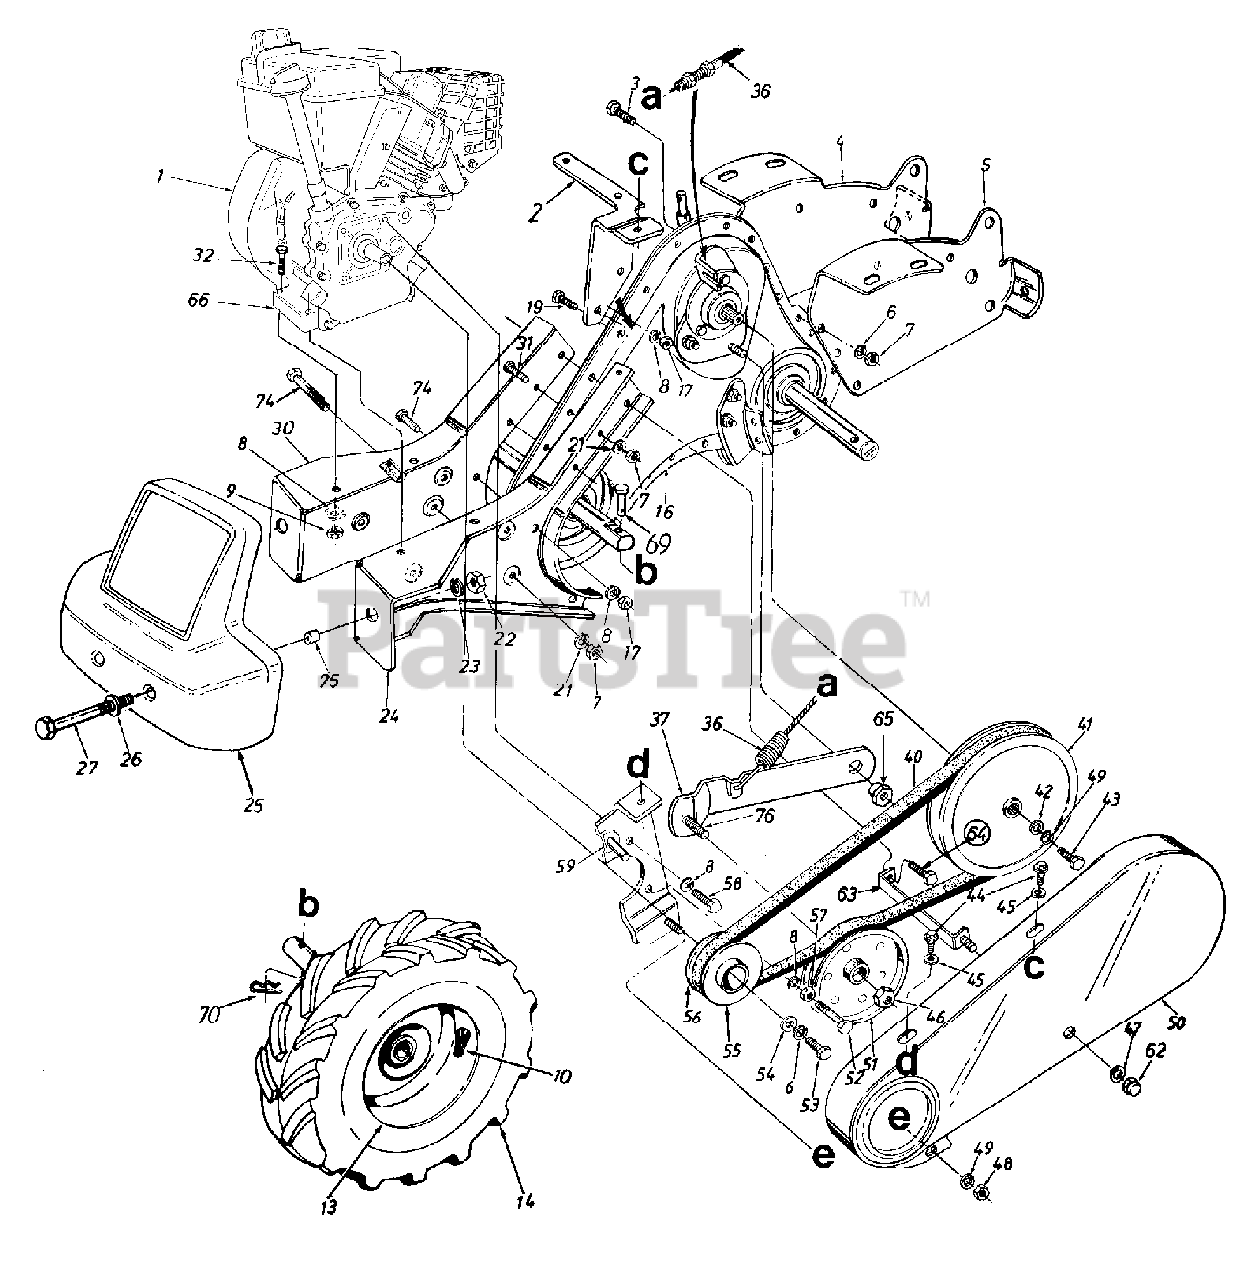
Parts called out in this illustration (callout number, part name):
1	Engine
7	Hex Nut 3/8-16 Thd.
8	L-Wash. 5/16" I.D.
9	Hex Nut 5/16-18" Thd.
10	Air Valve
16	Gear Case Ass'y. Comp.
19	Hex Bolt 5/16-18 x 1" Lg.
22	Hex Nut 1/2-20
23	L-Wash. 1/2" I.D.
26	Fl-Wash. .510" I.D. x 1.0"
27	Hex Bolt 1/2-20 x 5.5" Lg.
32	Hex Bolt 5/16-18 x 2.75"
36	Clutch Control Cable 46" Lg.
37	Idler Bracket
40	"V"-Belt
41	Fl-Pulley 8" O.D.
42	Fl-Wash. 1/4" I.D. x .93" O.D.
43	Hex Bolt 1/4-28 x .75" Lg.
44	Hx Wash. S-Tap Scr 1/4-20 x .50".
45	Fl-Wash. .281" I.D. x .625"
46	Jam Cnter L-Nut 3/8-16 Thd.
47	Fl-Wash. .266" I.D. x .625" O.D.
48	Hex Nut 1/4-20 Thd.
49	L-Wash. 1/4" I.D.
50	Belt Cover
51	Fl-Idler w/Flanges 3.75" O.D.
52	Hex Bolt 5/16-24 x 1.75"
53	Hex Bolt 3/8-24 x 1.00" Lg.
55	Outer Engine Pulley Half
56	Inner Engine Pulley Half
57	Hex Nut 5/16-24 Thd.
58	Hex Bolt 5/16-24 x .62" Lg.
59	Belt Keeper Ass'y.
62	Hex Cap Nut 1/4-28 Thd.
63	Belt Cover Brkt. Ass'y.
64	Hex Bolt 5/16-18 x 1" Lg. (Gr. 5)
65	Shld. Nut
66	Engine Spacer Block
69	Clevis Pin
70	Hairpin Clip
74	Screw 5/16-18 x 1"
76	Hex Cap Scr. 2/8-16: 1.25 Lg.
